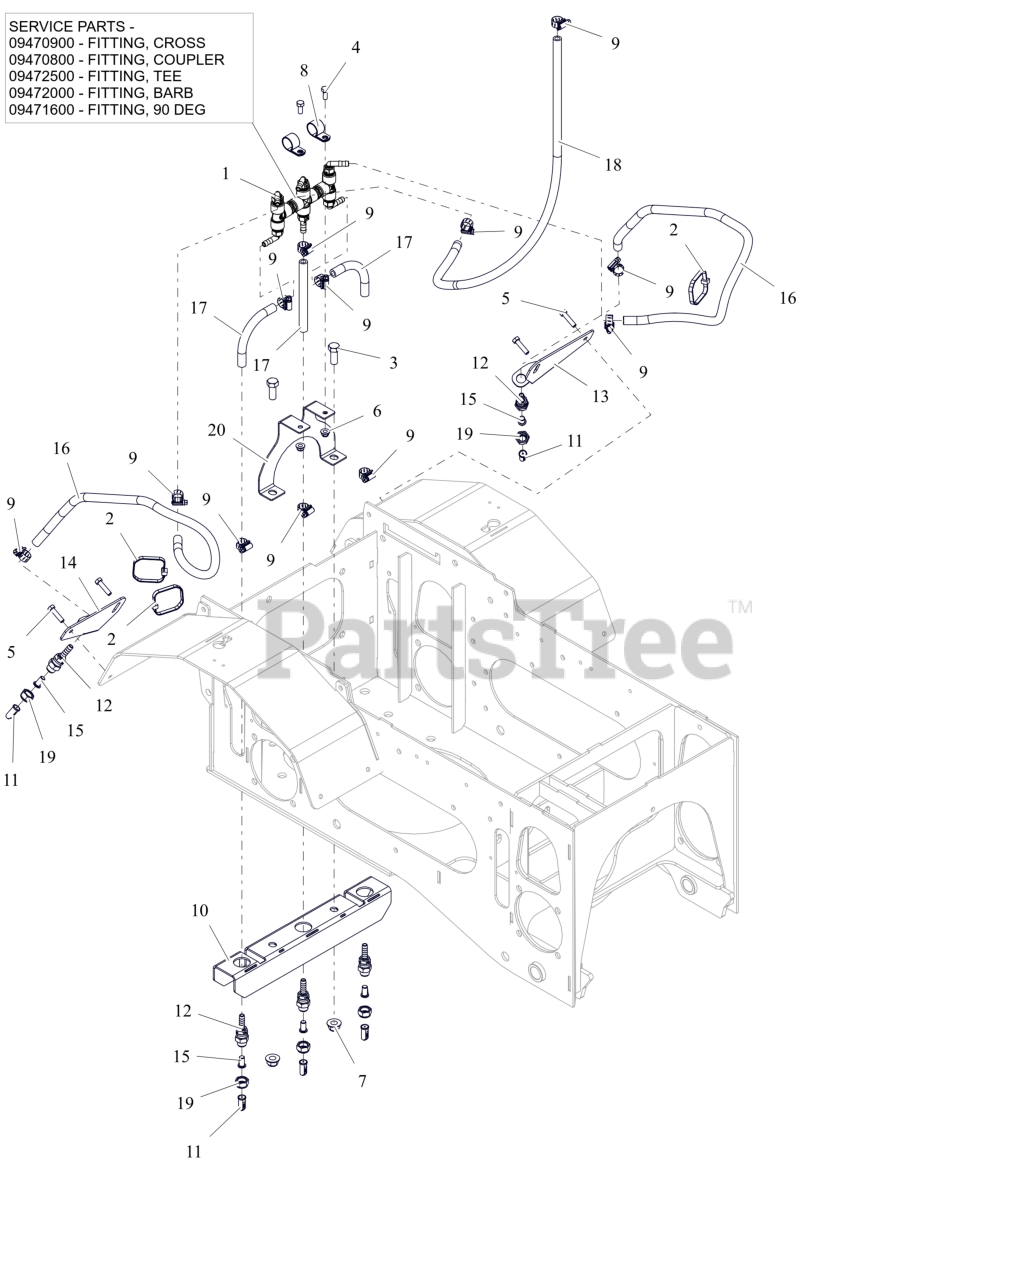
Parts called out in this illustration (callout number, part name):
1	ASM- MANIFOLD
1	FITTING- CROSS 3/8" FNPT
1	FITTING-COUPLER-SHORT 3/8 MNPT
1	FITTING- TEE 3/8" FNPT
1	FITTING-HOSE-3/8 MNPTX3/8 BARB
1	FITTING-HOSE-90 3/8MNPT X 3/8B
2	TIE WRAP, 15.25" X 120 LBS
3	BLT,HEX .50-13X1.25 G5 ZCC
4	BLT,HEX .31-18X.75 G5 ZCC
5	BLT, HEX .31-18X1.25 G5 ZCC
6	NUT,LK-NYL-FLG .31-18 G5ZC120
7	NUT,NYL-FLG .50-13 GF ZCC
8	CLAMP, COUSHIONED STEEL REV
9	CLAMP-HOSE WRM .44/.78X.53 F06
10	PLATE- SHIELD BRINE NOZZLE
11	SPRAY TIP- NOZZLE
12	BODY- NOZZLE
13	BRKT- GROUND BRINE SPRAY LH
14	BRKT- GROUND BRINE SPRAY RH
15	FILTER- NOZZLE W/ CHECK
16	HOSE-.375X.625X35.00
17	HOSE-.375X.625X6.25
18	HOSE-.375X.625X41.00
19	RETAINER- NOZZLE
20	BRKT- MANIFOLD MOUNT
